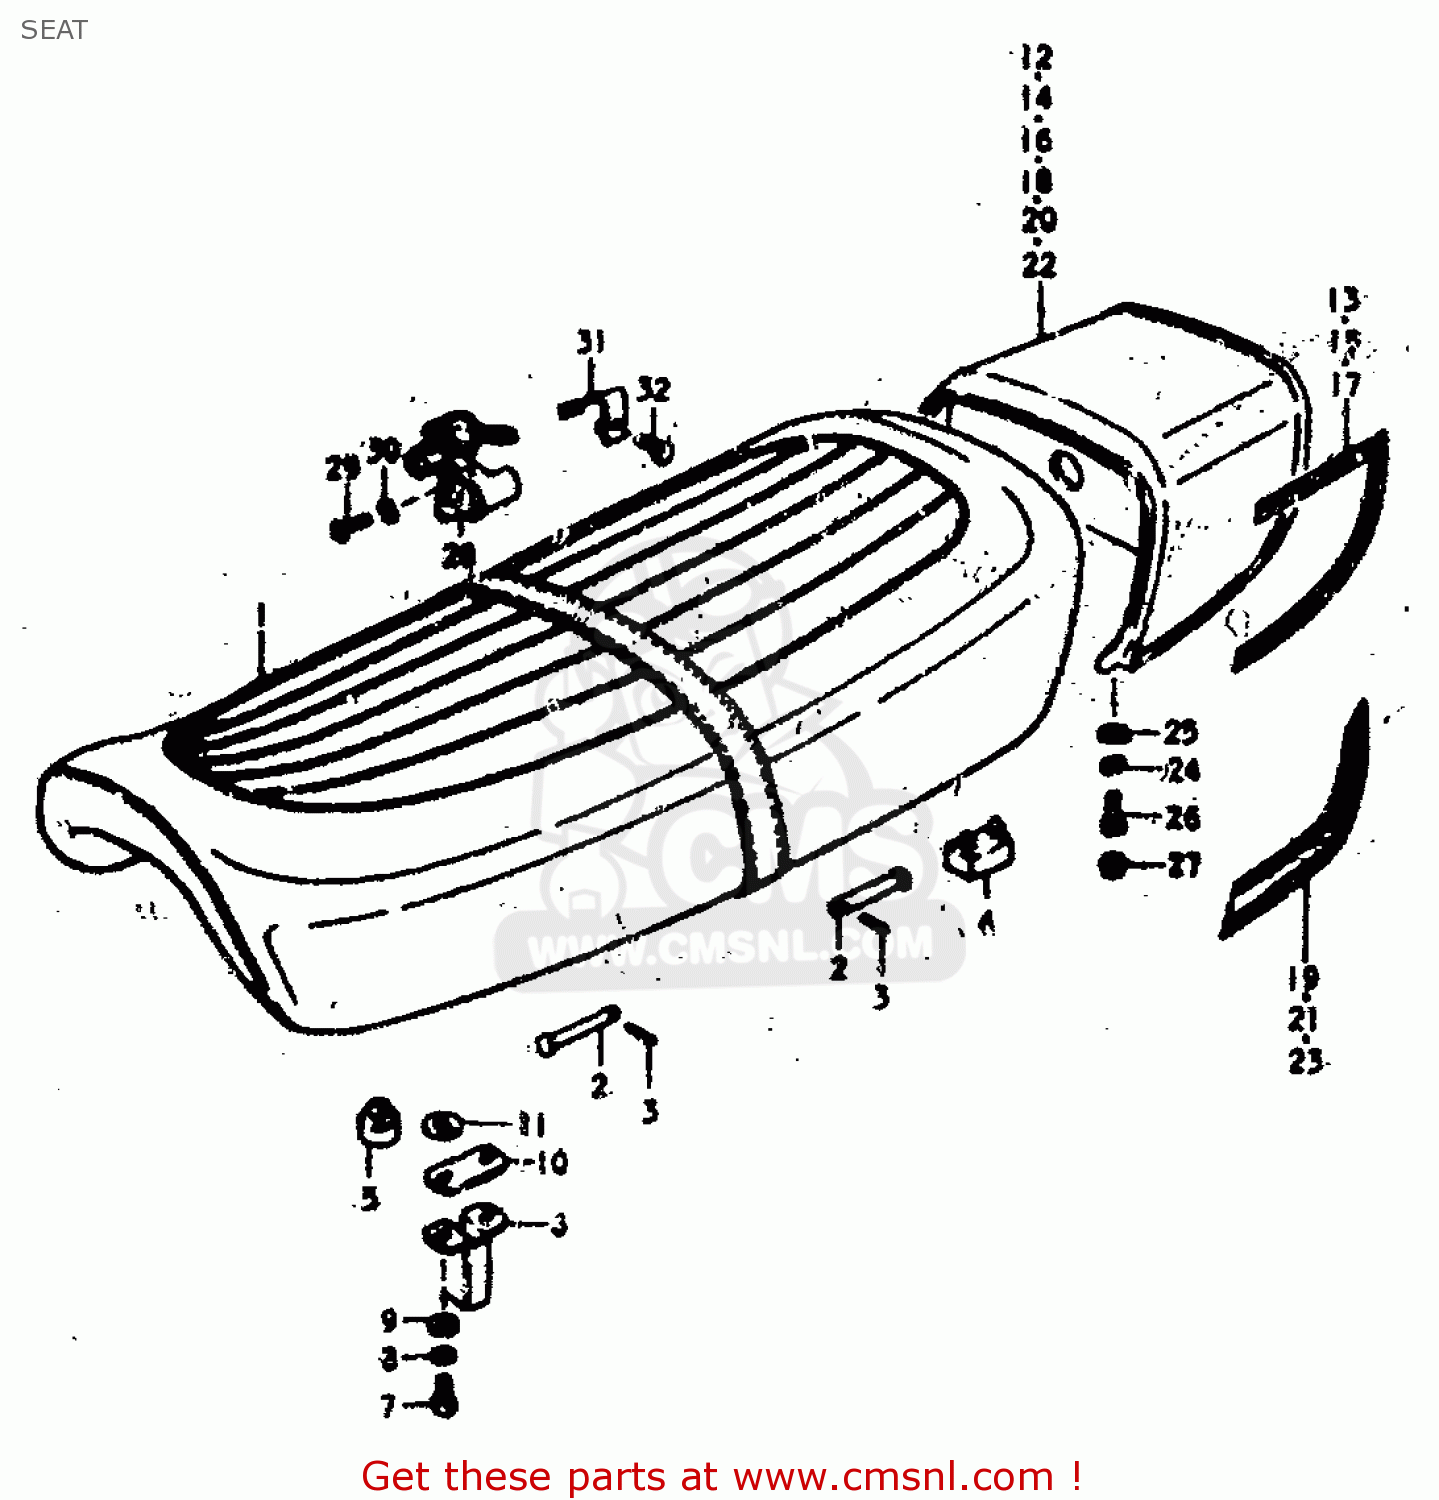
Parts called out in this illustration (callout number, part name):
1	SEAT ASSEMBLY
2	PIN
3	PIN
4	CUSHION
5	CUSHION(11.5X22X20)
6	STRIKER,SEAT LOCK
7	BOLT
8	LOCK WASHER
9	WASHER
10	SHIM,SEAT LOCK STRIKER
12	COVER,SEAT TAIL
13	TAPE SET
14	COVER,SEAT TAIL
15	TAPE SET
16	COVER,SEAT TAIL
17	TAPE SET
24	LOCK WASHER
25	WASHER
26	BOLT, UPPER
28	LOCK ASSEMBLY,SEAT
29	SCREW
30	LOCK WASHER
31	SPRING,HELMET HOLDER
32	BOLT 5X16
